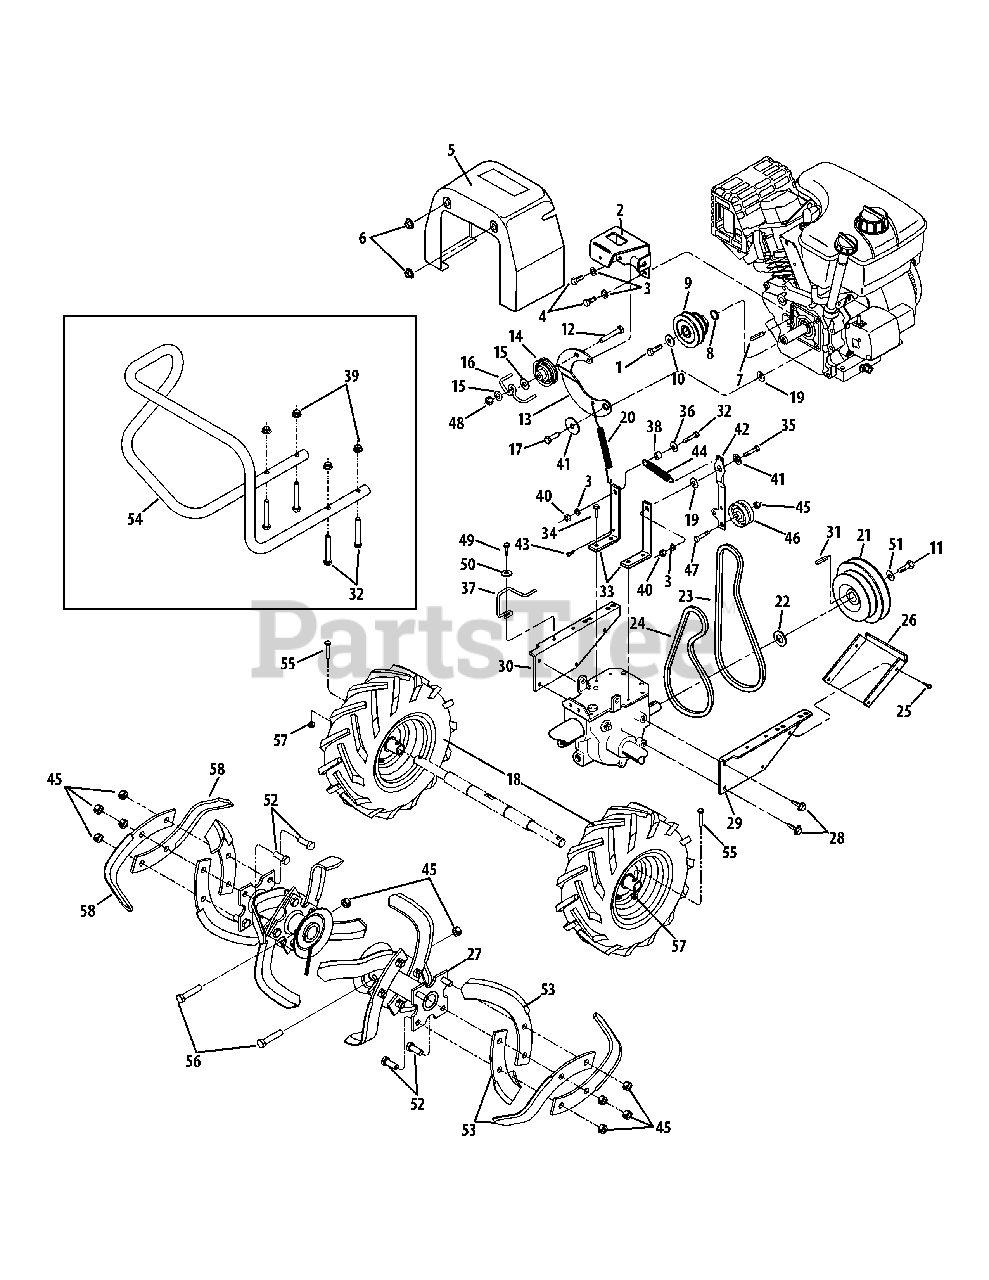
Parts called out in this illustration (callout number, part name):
1	Hex Screw, 3.8-24 x 2.25
1	Screw, 5.16-24 x 1.25
4	Hex Head Screw, 5.16-24 x 1.2
6	Flange Lock Nut, 5.16-18
7	Key, 3.16-2
7	Key, 3.16 x 1.5
9	Engine Pulley
10	Belle. Washer, .344 x 1.0 x .063
10	Belle. Washer .827 x .331 x .098
11	Hex Head Screw, 5.16.24 x 1-1.8
12	Hex Head Screw, 5.16.18 x 2
13	Reverse Idler Arm
14	Reverse Idler Pulley
15	Flat Washer, 5.16
16	Wire Formed Belt Guide
17	Hex Head Screw, 5.16-24 x 1
18	Wheel Assembly, 13 x 5 x 6
19	Flat Washer, 1-1.8
20	Reverse Return Spring
21	Transmission Pulley
22	Support Washer
23	Reverse Clutch Belt
24	Forward Clutch Belt
25	Self-tapping Screw, #10-32 x 1.2
26	Belts/Pulleys Guard
28	Hex Flange Screw, 5.16-18 x 3.4
29	Engine Support Bracket (left side)
30	Engine Support Bracket (right side)
31	Key, 3.16 x 1.50
32	Hex Head Screw, 5.16.18 x 2-1.4
33	Mounting Bar
34	Hex Flange Screw, 5.16-18 x .75
35	Hex Head Screw, 5.16-18 x 1-1.2
36	Flat Washer, 5.16
37	Belt Guide
38	Pivot Bushing
39	Hex Lock Nut, 5.16-18
40	Hex Nut, 5.16-18
41	Shoulder Washer
43	Self-tapping Screw, #10-24
44	Spring
45	Hex Locknut, 5.16-18
46	Forward Idler Pulley
47	Screw, 3.8-16 x 1-3.4
48	Hex Lock Nut, 5.16-18
49	Screw, 1.4-20 x 3.4
50	Flat Washer, 1.4
51	Belleville Washer, .827 x .331 x .098
52	Hex Head Screw, 3.8-16 x 1
53	Bolo Tine-single (Left)
55	Hex Head Screw, 1.4-20 x 1.5
56	Hex Head Screw, 3.8-16 x 2
57	Flange Hex Locknut, 1.4-20
58	Bolo Tine-single (Right)
